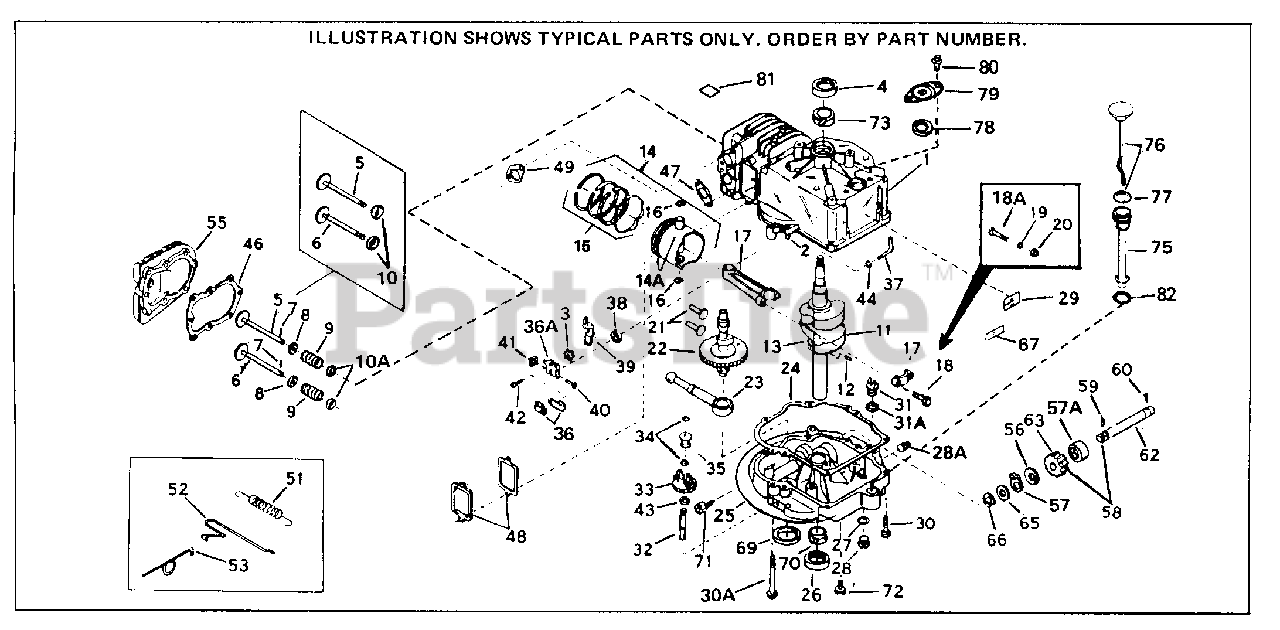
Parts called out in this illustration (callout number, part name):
1	"Cylinder (Incl. 2,4,67,78,79,80) 2-1/ 2"
2	Dowel Pin
4	Seal, Oil
5	Intake Valve (Std.) (Incl. 151)
5	Exhaust Valve (1/32" OS) (Incl. 151)
6	Exhaust Valve (Std.) (Incl. 151)
6	Exhaust Valve (1/32" OS) (Incl. 151)
8	Cap, Upper valve spring Early prod.on ly
9	Spring, Valve
10	Cap, Lower valve spring
11	Crankshaft
12	Pin, Crankshaft gear Only)
13	Crankshaft Gear Early Production Only
14	Piston, Pin & Ring Set (Std.) 2-1/2"B ore
14	Piston, Pin & Ring Set (.010" OS)
14	Piston, Pin & Ring Set (.020" OS)
14A	Piston & Pin Ass'y. (Std.)(Incl. 16) 2-1/2"
14A	Piston & Pin Ass'y. (.010" OS) Incl. 16
14A	Piston & Pin Ass'y. (.020" OS) Incl. 16
15	Ring Set (Std.)
15	Ring Set (.010" OS)
15	Ring Set (.020" OS)
16	Piston Pin Retaining Ring
17	Rod Assy., Connecting (Incl. 18)
18	Connecting Rod Bolt Used on late prod uction
18A	Connecting Rod Bolt Early production
19	Connecting rod bolt washer Early prod uction
20	Lock Nut (Used on early production)
21	Valve Lifter
22	Camshaft (No Compression Release)
23	Oil Pump Ass'y.
24	Mounting Flange Gasket
25	Flange Ass'y. Incl. 26, 27, 28, 32 &5 7A
26	Oil Seal
27	Drain Plug Gasket
28	Oil Drain Plug (Sq. hd., 1/4-18)
28	Plug, Oil drain
29	Decal, Instruction
30	Screw, 1/4-20 x 1-1/4"
30A	Screw, 1/4-20 x 2-1/4"
31	Oil Fill Plug (Incl. 312) also availa ble in Packaged Part #740079
31A	Oil Fill Plug Gasket
32	Shaft, Mechanical governor
33	Gear Assy., Governor (Incl. 43)
34	Retaining Ring
35	Spool, Governor
36	Clamp, Governor lever
37	Rod, Governor
39	Lever, Governor
42	Screw, 8-32 x 5/16" (Use as required)
43	WASHER
44	Flat Washer
46	Cylinder Head Gasket
47	Intake Pipe Gasket
48	Valve Cover Gasket quired)
48	Gasket, Valve spring cover
49	Gasket, Intake pipe
51	Governor Lever Spring Use as required
52	Governor Link (Use as required)
53	Control Lever Spring Use as required
55	Head, Cylinder Not Incl. with shortbl ock
56	Washer, Thrust
57	Washer, Tang
57A	Seal, Oil
60	Pin, P.T.O. (Use as required)
62	Shaft, P.T.O. (Incl. 65)
63	Gear, Worm
65	Washer, Flat
66	Ring, Retaining
67	Decal, Model & Serial number
78	Breather Gasket (Use as required)
79	Breather Cover (Use as required)
80	Screw, 10-24 x 9/16"
81	Decal, Name (Use as required)
